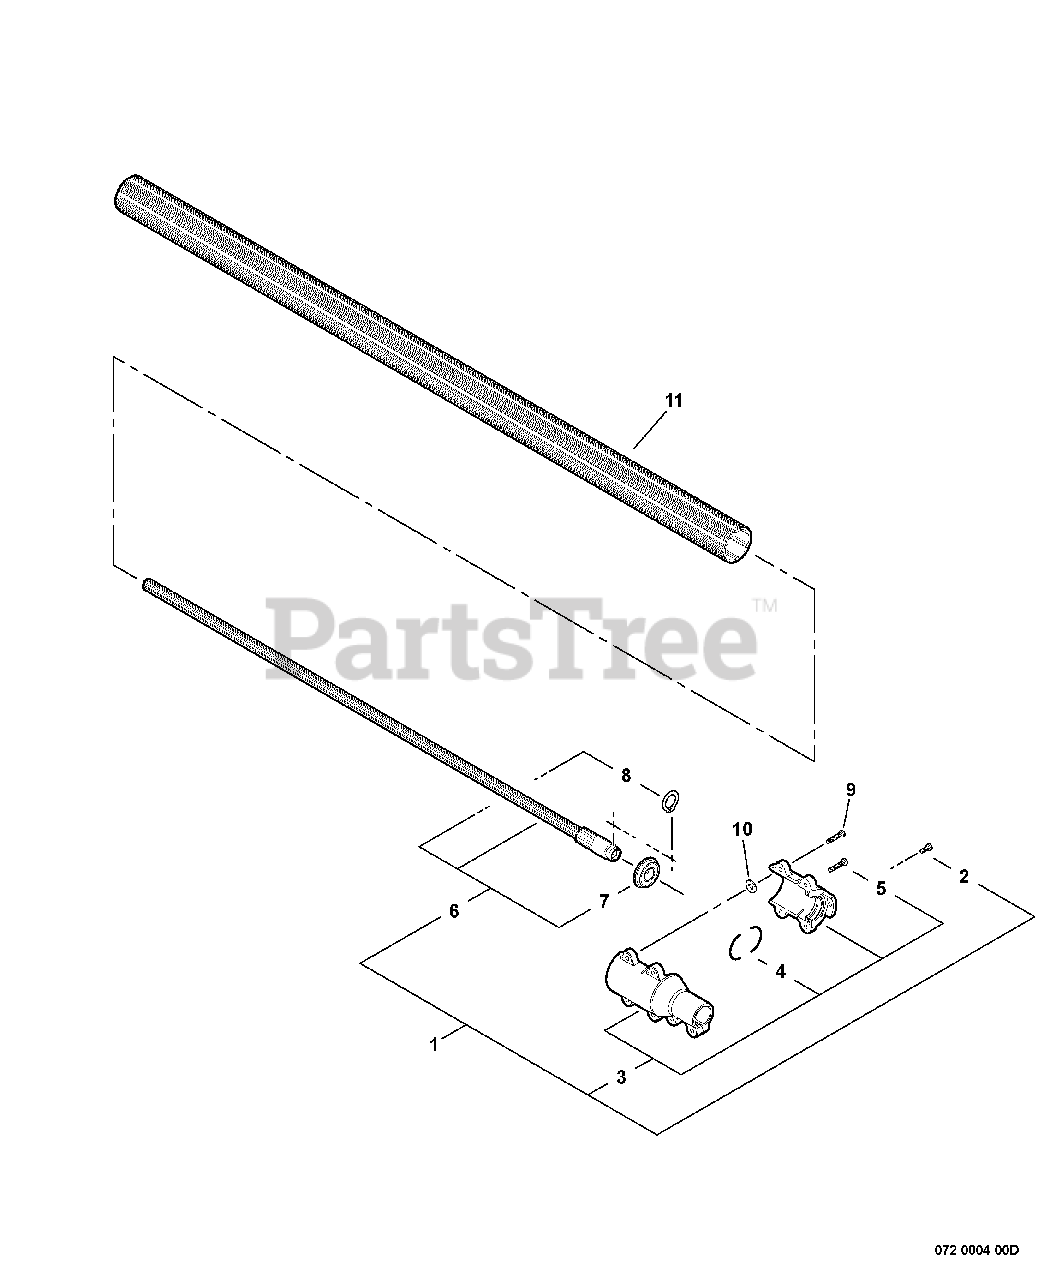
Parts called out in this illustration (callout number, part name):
1	COUPLING/DRIVESHAFT ASSY
2	BOLT 5×14
3	COUPLING ASSY, LOWER
4	CUSHION
5	BOLT 5×20
6	DRIVESHAFT ASSY, LOWER
7	BEARING, BALL 15×32×9
8	RING, RETAINING
9	BOLT 5×20
10	WASHER 5
11	PIPE, MAIN - ORANGE
